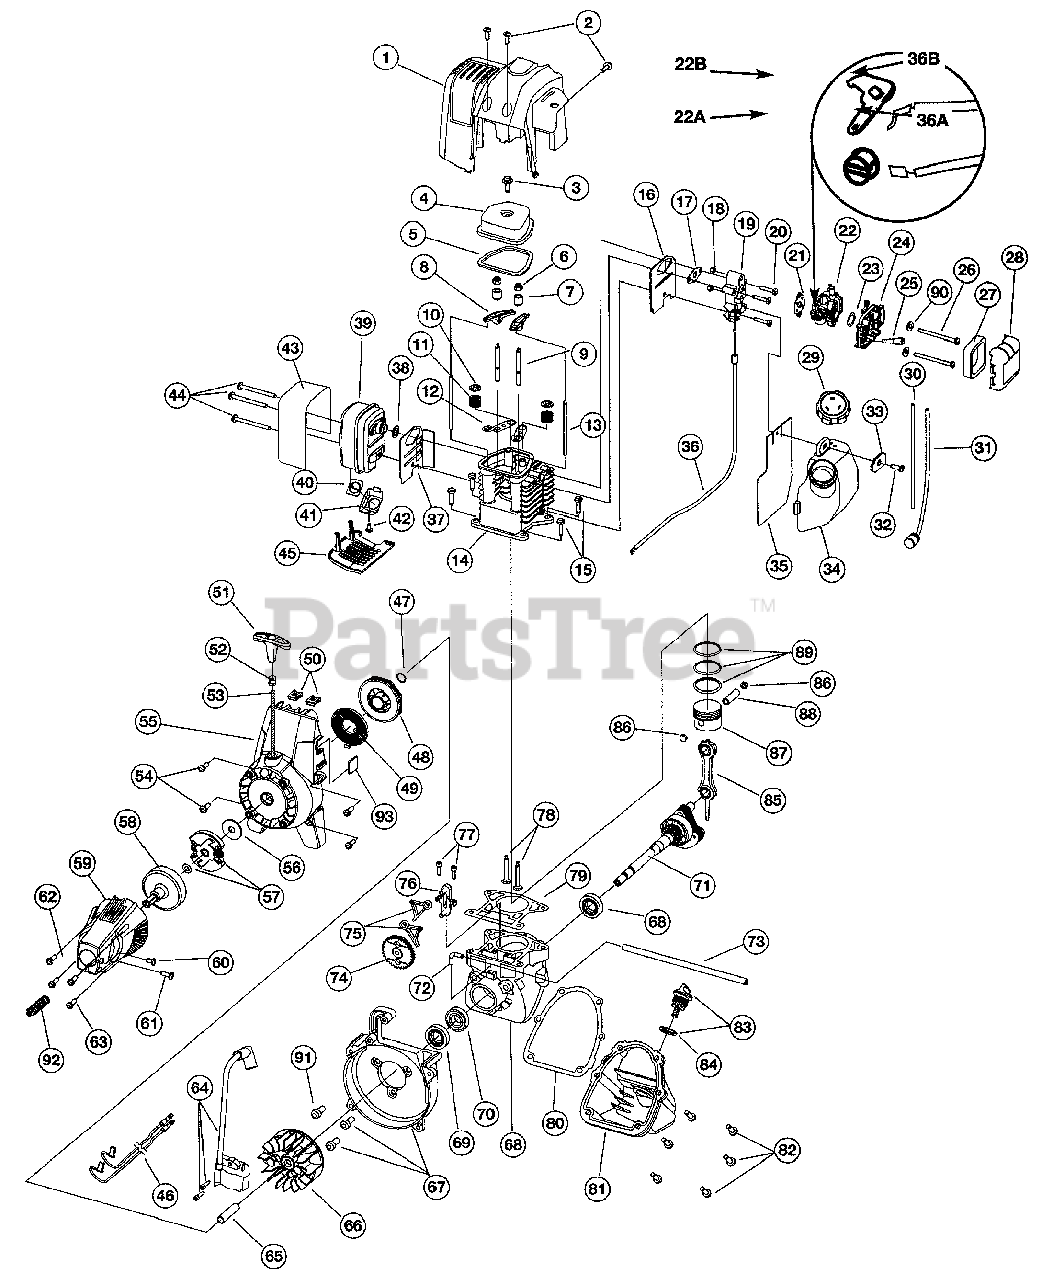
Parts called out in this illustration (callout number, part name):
1	Engine Cover
2	Engine Cover Screws
3	Valve Cover Screw
4	Valve Cover
5	Valve Cover Gasket
6	Rocker Adjustment Nut
7	Rocker Arm Pivot
9	Rocker Arm Stud
10	Valve Spring Retainer
11	Valve Spring
12	Push Rod Guide
13	Push Rod
14	Cylinder Head
15	Cylinder Screw
16	Intake Baffle
17	Carburetor Mount Gasket
18	Nut
19	Carburetor Mount
20	Carburetor Mount Screw
21	Carburetor Gasket
22A	Carburetor with Primer
22B	Carburetor with Primer
23	O-Ring, Carburetor
24	Air Filter/Choke Cover Assembly
25	Breather Tube
26	Air Filter Mounting Screw
28	Air Filter Cover
30	Fuel Return Line
31	Fuel Pick-Up Line with Filter
34	Fuel Tank Assembly
35	Fuel Tank Shield
36A	Throttle Cable
36B	Throttle Cable
37	Muffler Baffle
38	Muffler Gasket
39	Muffler
40	Spark Arrestor Screen
41	Screen Cover
43	Muffler Shield
44	Muffler Mounting Screw
45	Muffler Cover
46	Switch Wire Assembly
47	Palnut
48	Recoil Pulley
49	Recoil Spring
51	Pull Handle
54	Starter Housing Screw
55	Starter Housing Assembly
56	Clutch Washer
57	Clutch with Spacer
58	Clutch Drum
59	Clutch Cover
60	Anti-Rotation Screw
61	Screw
63	Clutch Cover Screw
64	Ignition Module with Screws
66	Flywheel
67	Shroud Assembly with Screws
68	Crankcase Assembly
73	Breather Hose
75	Cam Follower Set
76	Cam Bracket
77	Cam Bracket Screw
78	Valves, Intake and Exhaust
79	Cylinder Gasket
80	Oil Pan Gasket
81	Oil Pan
82	Oil Pan Screw
83	Dipstick Assembly
85	Connecting Rod
86	Wrist Pin Button
87	Piston
89	Piston Ring Set
92	Compression Spring
